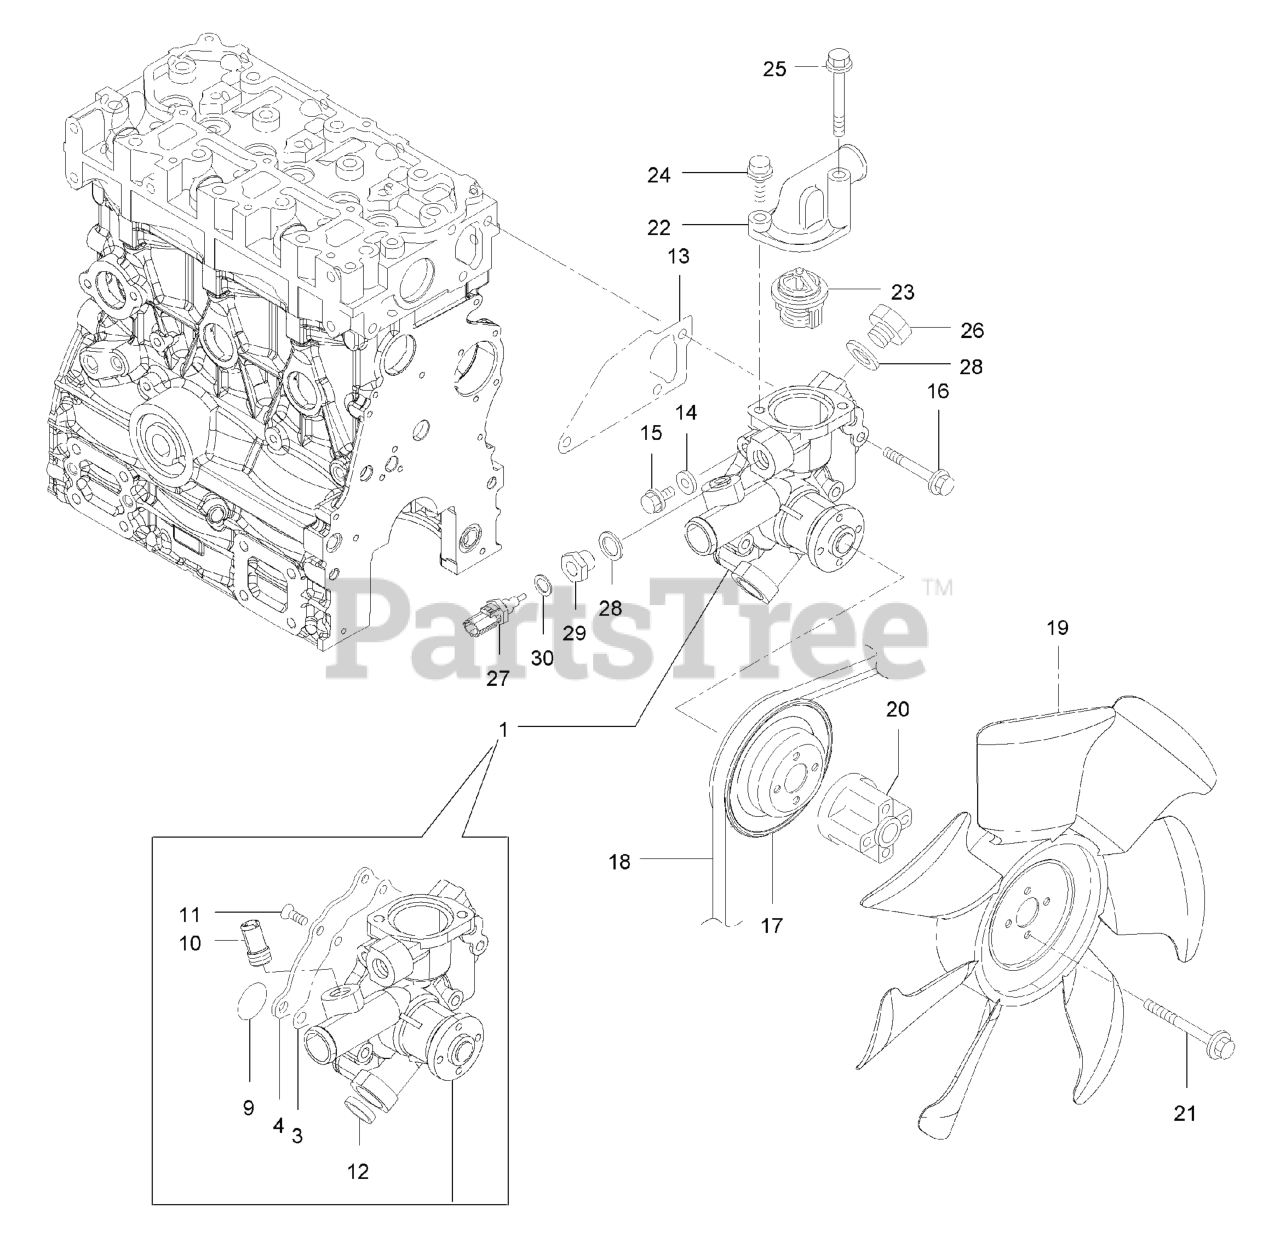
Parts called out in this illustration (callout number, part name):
1	PUMP ASM-WATER
10	JOINT-PIPE
13	GASKET-WATER PUMP
17	V-PULLEY
19	FAN-COOLING 1
20	SPACER-FAN
22	COVER-THERMOSTAT
23	THERMOSTAT
27	SENSOR-THERMOSTAT, CW
30	WASHER-SEAL
